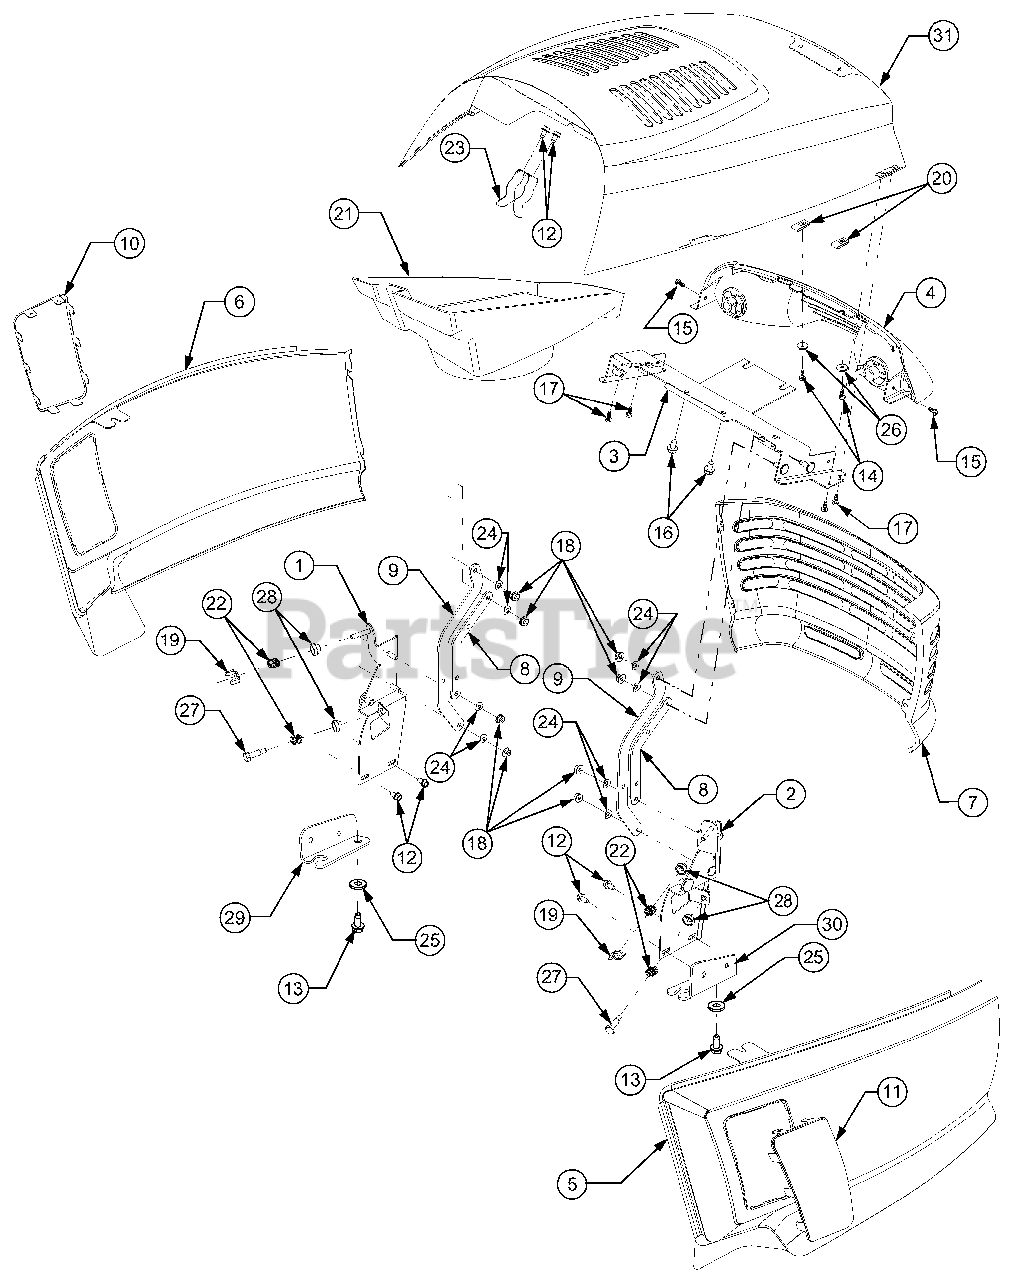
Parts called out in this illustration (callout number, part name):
1	Bracket Assembly, Grille LH
2	Bracket Assembly, Grille RH
9	Link, Hood, Rear
13	Screw, Hx Wash. Hd Tapp, 5/16-18 x .75
14	Screw, Hx Tapp, 10-16 x .625
15	Screw, Hx Wash. Hd Tapp, 10-16 x .5
16	Screw, Hx Wash. Hd Tapp, 5/16-12 x .75
17	Screw, Truss Phillips Tapp, 10-16 x .5
18	Nut, Flange Lock, 1/4-20
19	Nut, Wing, 1/4-20
20	Nut, Speed, 10z U-type
21	Plenum, Hood
22	Spring, Compression, .50 OD x .5 Lg
23	Spring, Latch, Hood
24	Washer, Spring, .265 x.562 x.025
25	Washer, Flat, .385 x 1.0 x .135
26	Washer, Flat, .194 x .62 OD x .063
27	Screw, Shoulder, .31x .75, 1/4-20
28	Bushing, Tapered, .32 ID x .69 OD
